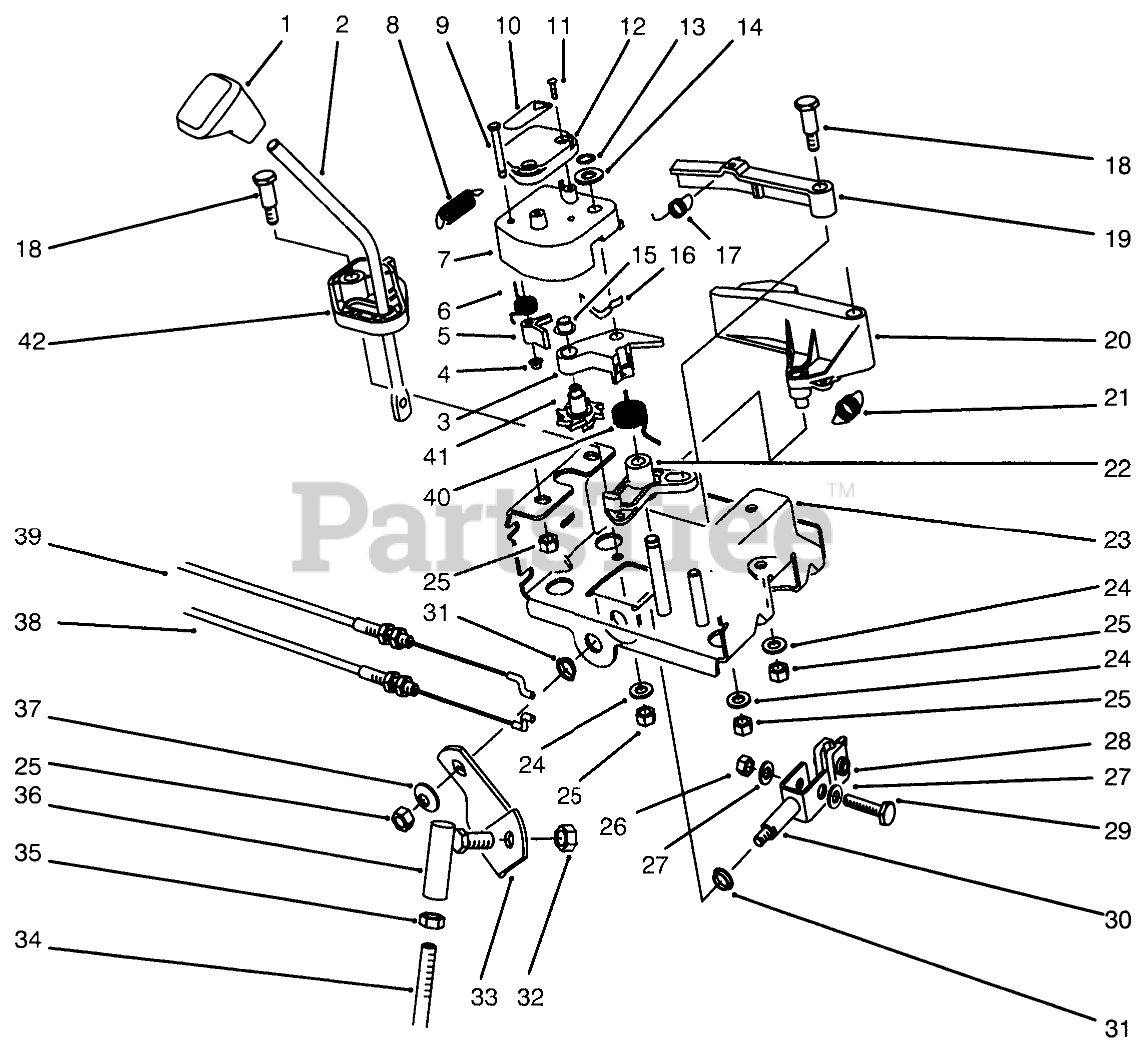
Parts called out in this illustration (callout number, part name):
1	KNOB-SHIFT
2	ROD-SHIFT
3	LEVER-WHEEL, INDEX
4	NUT-PUSH
5	TANG-INDEX
6	SPRING-TORSION
7	LATCH-LEVER
8	SPRING-EXTENSION
9	PIN-TANG
10	DECAL
11	SCREW-PPH
12	COVER-LATCH
13	RING-RETAINING
14	WASHER-THRUST
15	RETAINER-PUSH ON
16	SPRING-FLAT
17	SPRING-EXTENSION
18	SCREW-SHOULDER
19	LEVER-LOCKOUT
20	LEVER-REVERSE
21	SPRING-EXTENSION
22	LEVER-REVERSE, SWITCH
23	Frame-Control
24	WASHER-PLAIN
25	NUT-LOCK, NI
26	NUT-LOCK, NI
27	WASHER-FLAT
28	RETAINER-ROD, SHIFT
29	SCREW-HH
30	CLEVIS ASM
31	BUSHING
32	NUT-LOCK, NI
33	BRACKET-SHIFT
34	ROD-BENT SHIFT, LOWER
35	NUT-HJ
36	JOINT-BALL
37	WASHER-BELLEVILLE
38	CABLE-GEARBOX
39	CABLE-ARM, LATCH
40	SPRING-TORSION
41	WHEEL-INDEX
42	BASE-LOCKOUT
